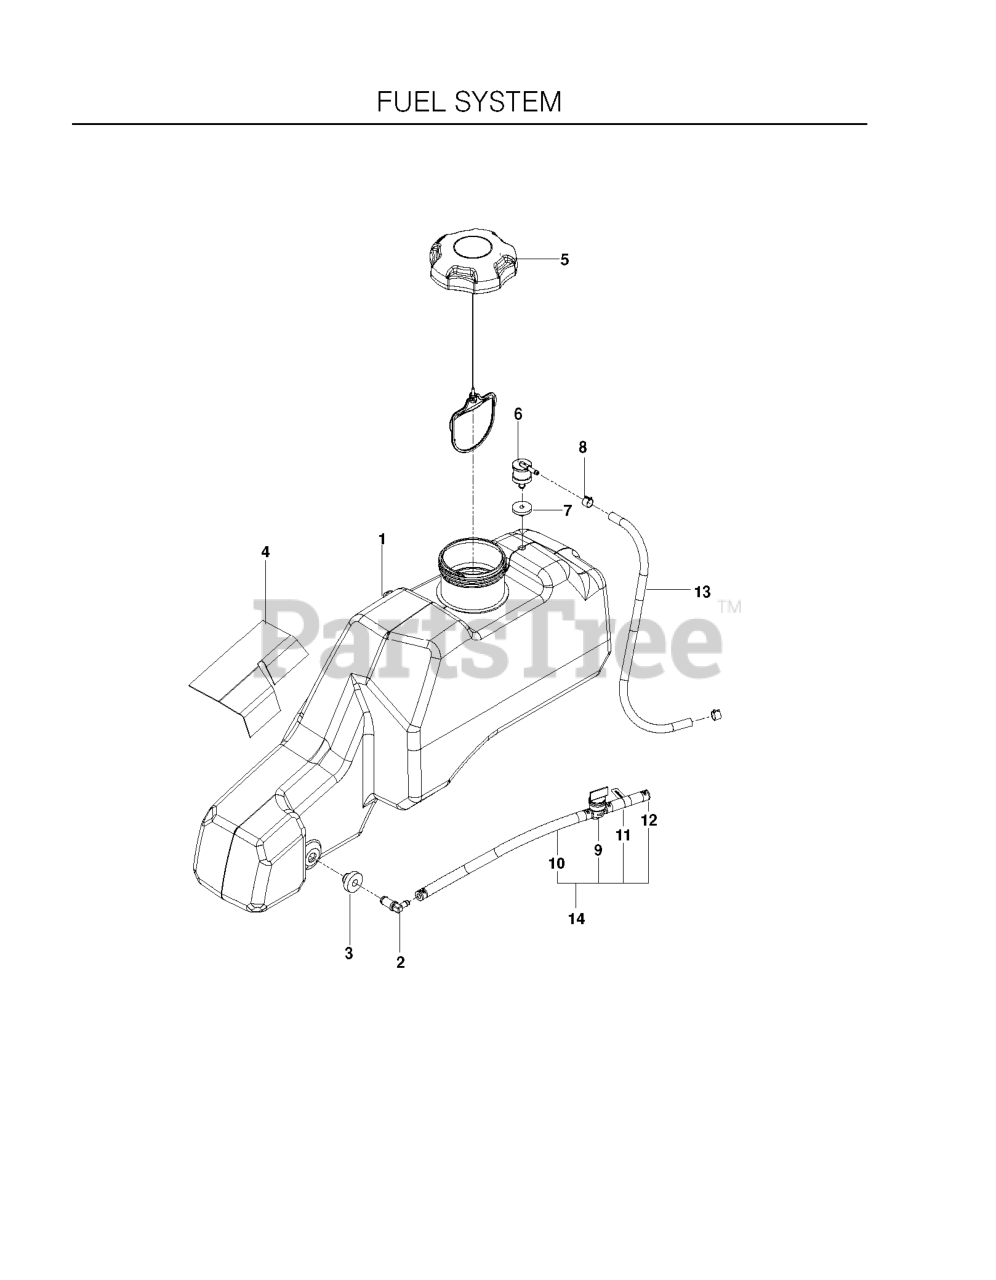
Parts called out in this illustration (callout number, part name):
1	TANK, FUEL, RT-EPA
2	STEM, FUEL TANK
3	RUBBER GROMMET
4	SHIELD, HEAT
5	CAP, FUEL
6	VALVE.FUEL.CHECK
7	GROMMET, CHECK VALVE
8	CLAMP, HOSE
9	FUEL VALVE
10	GAS LINE 10"
11	FUEL LINE 3"
12	HOSE CLAMP
13	HOSE, FUEL, 3/16" X 20"
14	FUEL LINE ASSY
